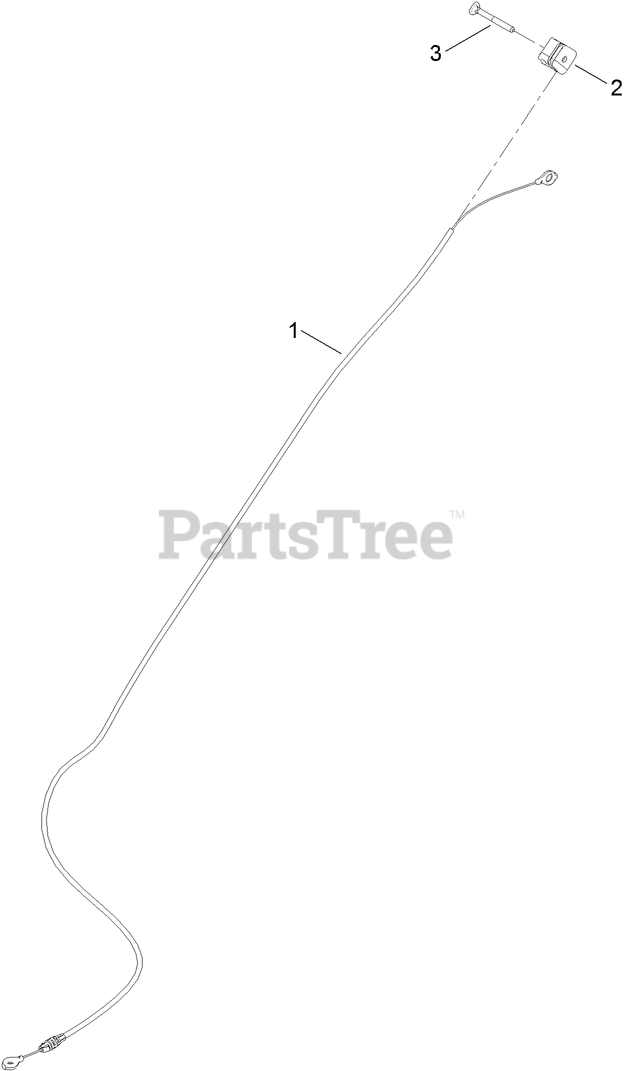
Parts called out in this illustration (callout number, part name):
1	CABLE-BRAKE
2	ANCHOR-CABLE
3	SCREW-HANDLE
